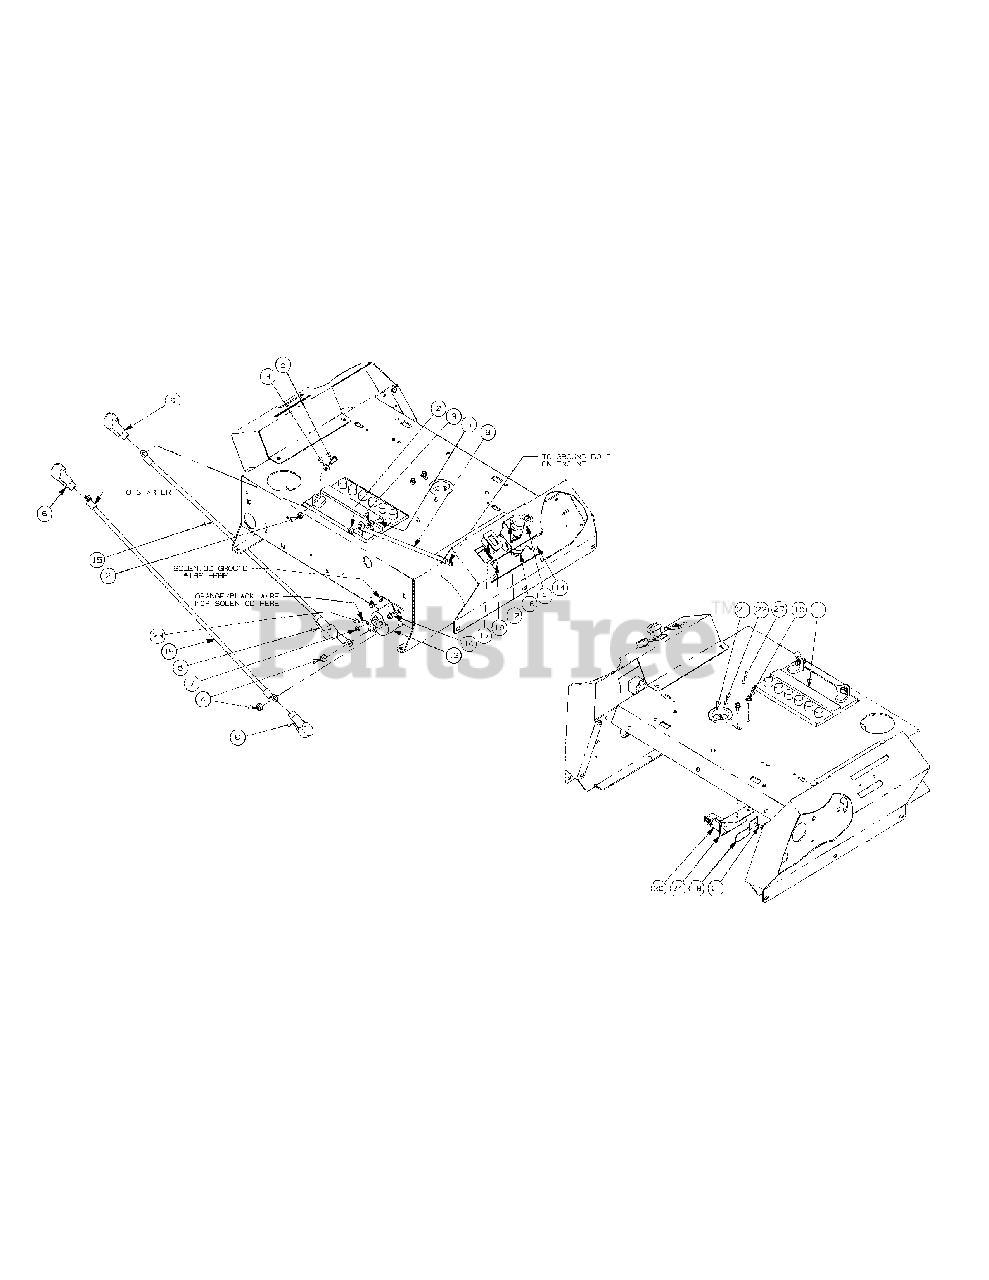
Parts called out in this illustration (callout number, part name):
1	Battery, 12V 225CCA 30Min
2	Lock Nut, Nylon Insert, 1/4-20
3	Flat Washer, 1/4
4	Nylock Nut, 5/16-18
5	Hex Cap Screw, 1/4-20 x .75
6	Boot, 1" OD Rubber Battery-PST Red
7	Lock Nut, Nylon Insert, 10-32
8	Cable, Battery, Black, 17"
9	Nut, 5/8-32, w/Cap
10	Self Tapping Screw, 1/4-20 x 1/2
11	Self Tapping Screw, 10-32 x 1/2
12	Electric PTO Switch
14	Relay, 12V 40A
15	Cable, Battery, Red, 24"
16	Switch, Ignition, 6 Pin
17	Hour Meter includes:
18	Safety Switch Retainer Spring
19	PTO Switch Bracket
20	Switch, Safety N.O./N.C.
21	Gromment, 1.5 ID x 2.13 OD
22	Electrical Conduit Clip, 3/8
23	Terminal Tab, 1/4" Blade
24	Brake Switch Mounting Bracket
27	Electrical Conduit Clip, 1/2
